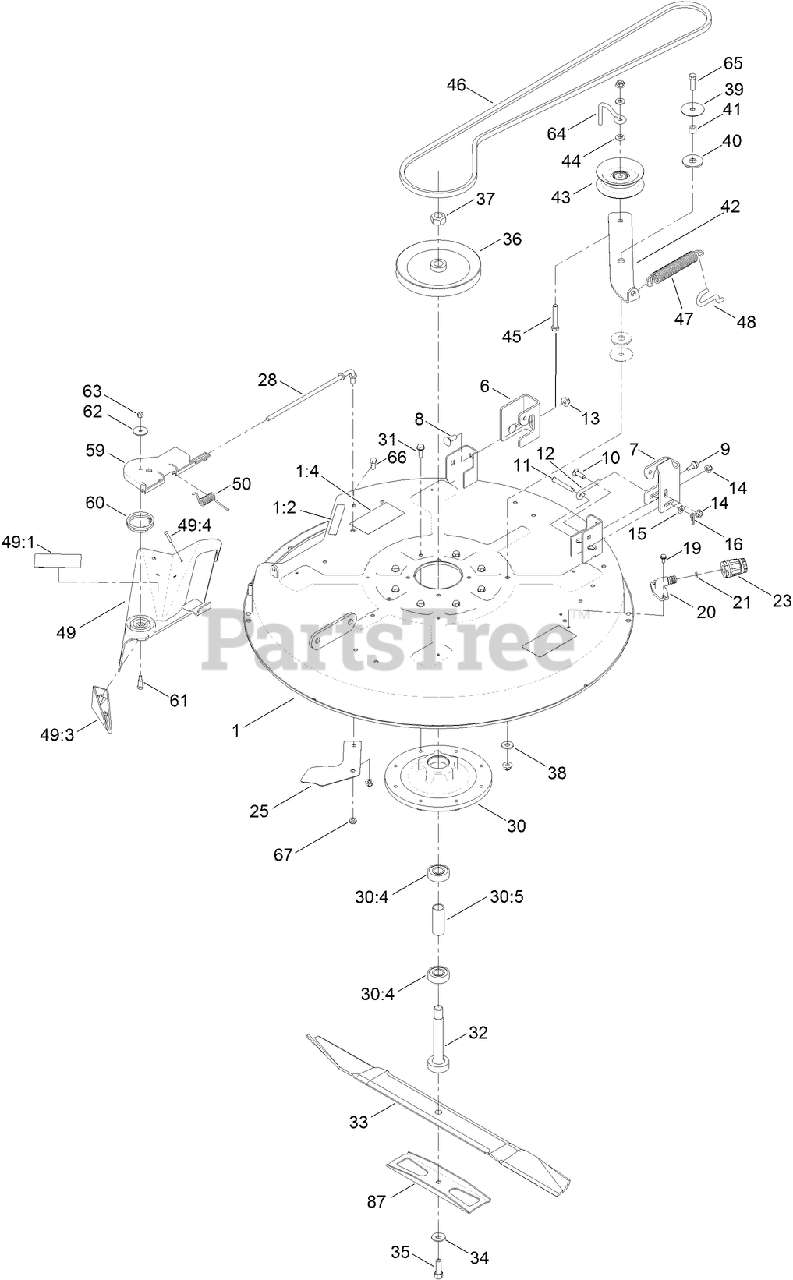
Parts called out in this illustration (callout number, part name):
1	32 INCH DECK AND DECAL ASM
1:2	DECAL-DANGER
1:4	DECAL-DANGER, DECK
6	BRACKET-HANGER, RH
7	BRACKET-HANGER, LH
8	BOLT-CARR
9	SCREW-SHOULDER,HWH
10	SCREW-CARR
11	PIN-CLEVIS
12	ROD-LEVEL, DECK
13	NUT-HF, NI
14	NUT-HF, NI
15	WASHER-PLAIN
16	PIN-COTTER
19	SCREW-HWH
21	O-RING
23	CONNECTOR-HOSE
25	RAMP-DEFLECTOR
28	ROD-PIVOT
30	SPINDLE HOUSING ASM
30:4	BEARING-BALL
30:5	SPACER-BEARING
31	SCREW-TAPTITE
32	SHAFT-SPINDLE
33	BLADE-RECYCLER, 31.35 INCH
34	WASHER-BELLEVILLE
35	SCREW-HH
36	PULLEY-DECK
37	NUT-HEX
38	WASHER-HARDENED
39	WASHER
40	WASHER-FRICTION, COMPOSITE
41	SPACER
42	ARM-IDLER
44	WASHER-FLAT
45	SCREW-HH
46	V-BELT, 81.8 INCH
47	SPRING-EXTENSION
48	HOOK-RETURN, SPRING
49	32 INCH DEFLECTOR ASM
49:1	DECAL-DANGER
49:3	KICKER
49:4	SCREW-PPH
50	SPRING-TORSION
59	PIVOT-HINGE, DEFLECTOR
60	SPRING-TORSION
61	BOLT-SHOULDER
62	WASHER-FLAT
63	NUT-LOCK, NI
64	GUIDE-IDLER, BELT
65	SCREW-HH
66	SCREW-HH
87	STIFFENER
